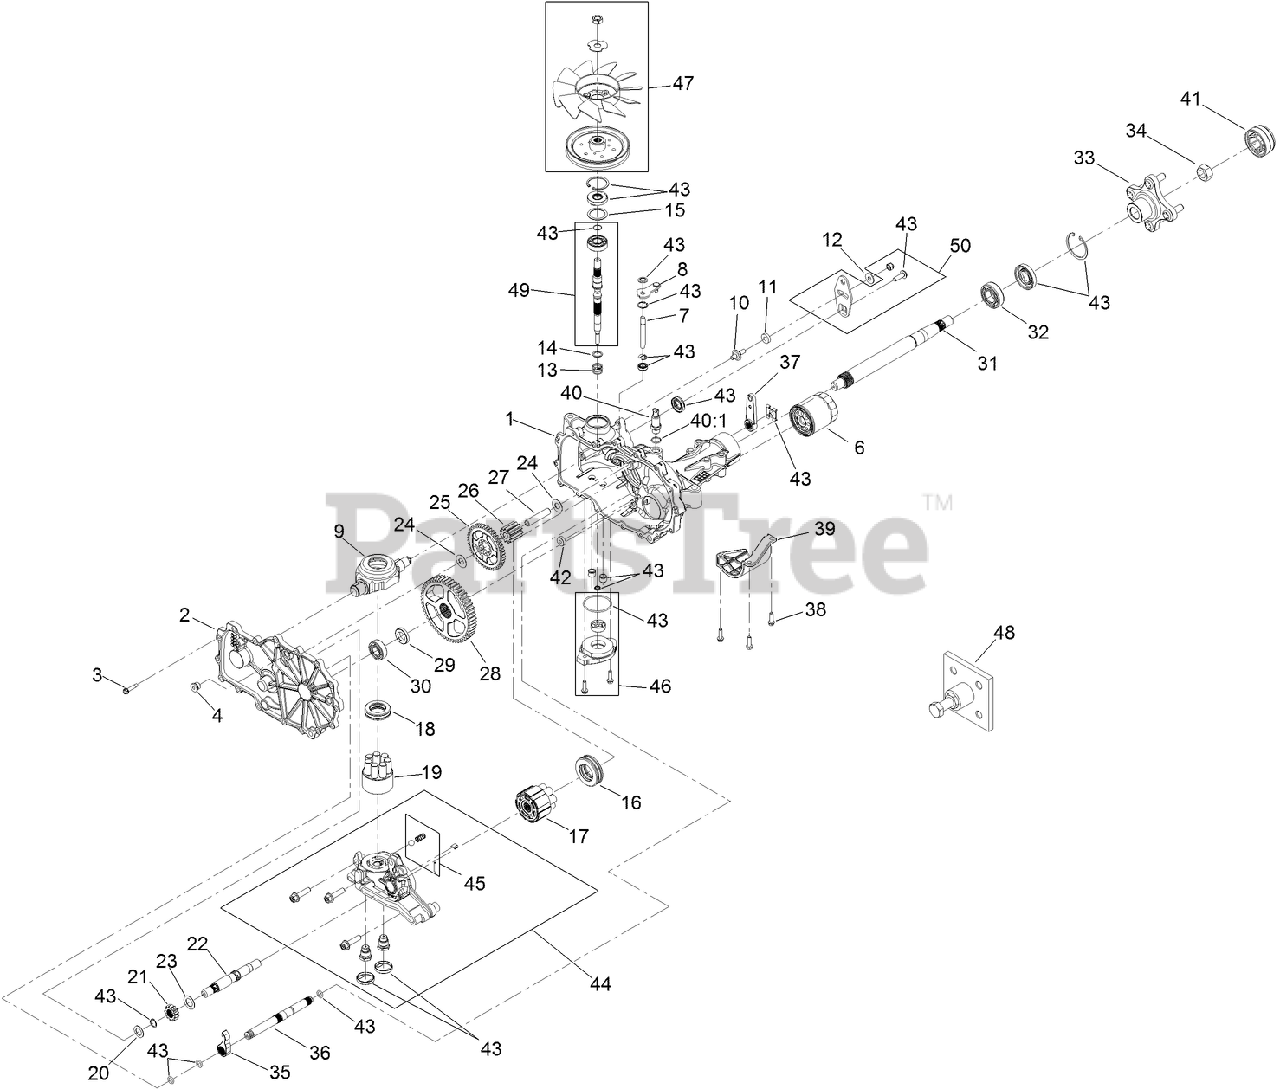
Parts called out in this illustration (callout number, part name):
1	RH MAIN HOUSING KIT
2	RH SIDE COVER KIT
3	SCREW-HHF
4	PLUG-THREAD, STRAIGHT
6	ELEMENT-OIL FILTER, HYD
7	ROD-BYPASS
8	ARM-BYPASS
9	SWASHPLATE-TRUNNION
11	PUCK-FRICTION
12	WASHER
13	SPRING-COMPRESSION
14	WASHER
15	SPACER
16	BEARING-THRUST
17	MOTOR CYLINDER BLOCK KIT
18	BEARING-THRUST, PLASTIC CAGE
19	7 PISTON BLOCK ASM
20	WASHER-FLAT
21	GEAR-13T
22	SHAFT-MOTOR
23	WASHER
24	WASHER
25	GEAR-46T
26	GEAR-11T
27	PIN-JACKSHAFT
28	GEAR-54T
29	SPACER
30	BEARING-BALL
31	SHAFT-AXLE
32	BEARING-BALL
33	HUB KIT
34	NUT-HUB
35	PAWL-BRAKE
36	BRAKE SHAFT KIT
37	HANDLE-BRAKE
38	SCREW-HF
39	GUARD-FILTER, RH
40	ADAPTER-STRAIGHT
40:1	O-Ring
41	COVER-NUT, AXLE
42	MAGNET-RING
43	SEAL KIT
44	RH CENTER SECTION KIT
45	CHARGE RELIEF KIT
46	CHARGE PUMP KIT
47	FAN AND PULLEY KIT
48	PULLER-HUB, 4 BOLT
49	INPUT SHAFT KIT
50	CONTROL ARM KIT
